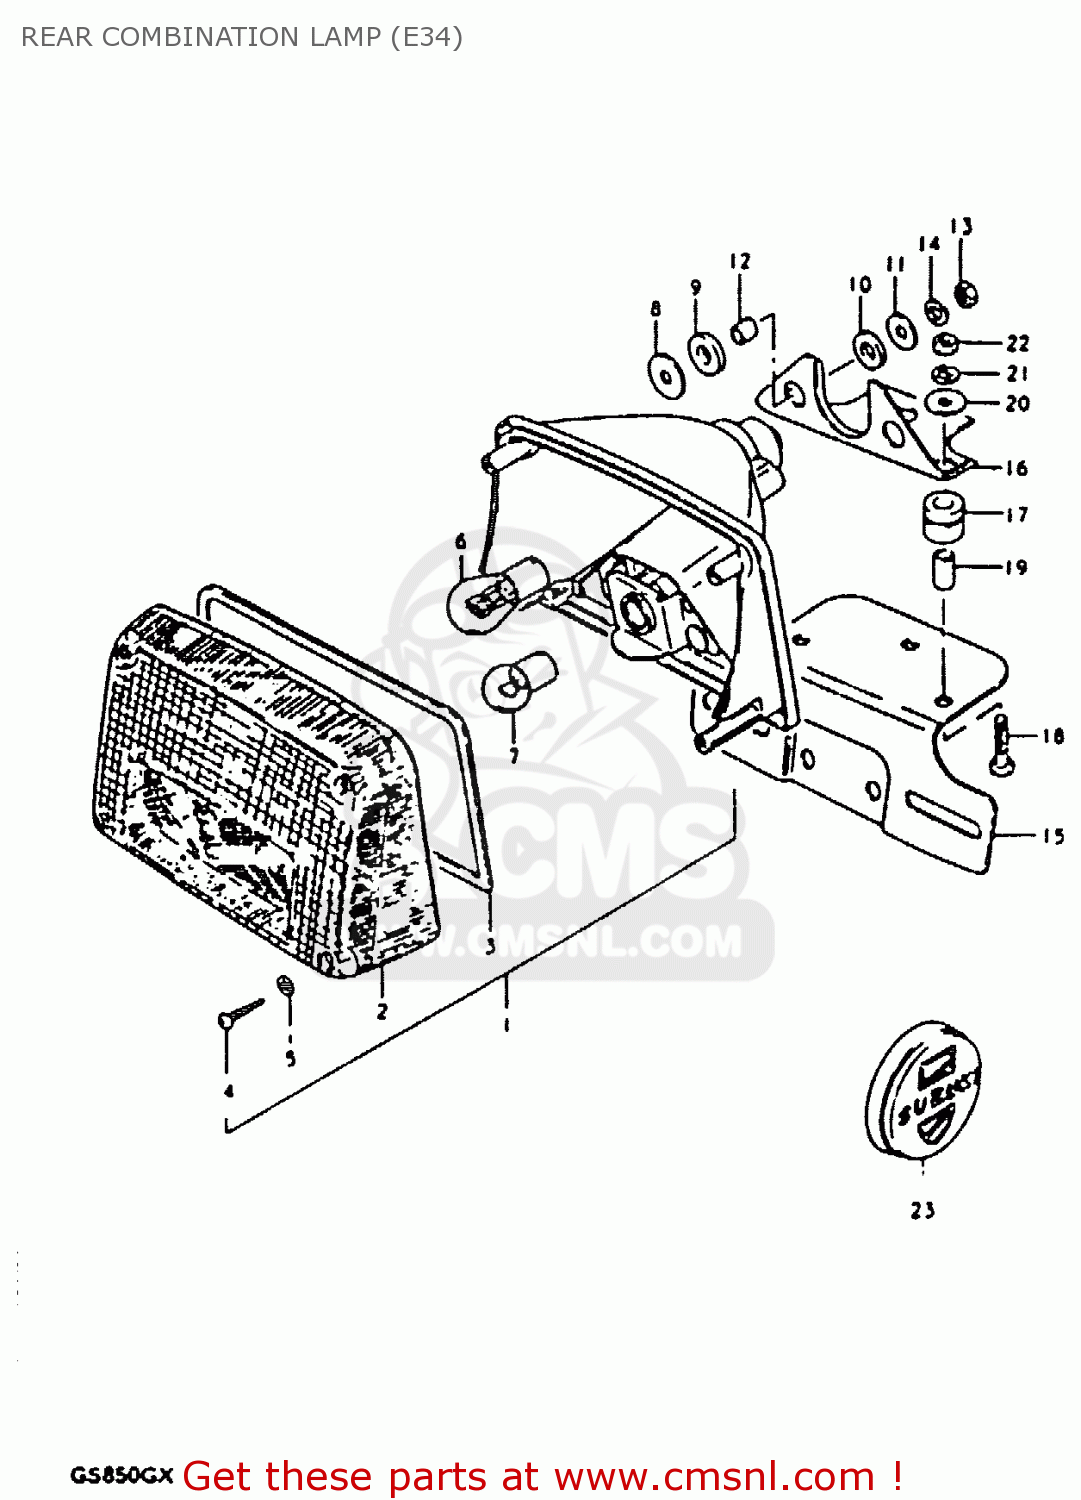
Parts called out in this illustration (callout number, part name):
1	LAMP, REAR COMBINATION
2	LENS
3	GASKET (NAS)
4	BOLT
5	GASKET (NAS)
6	BULB(12V21/5W)
7	BULB(12V10W,TOKAI DENSO)
8	WASHER
9	CUSHION
10	CUSHION
11	WASHER(6,5X22X1.6)
12	SPACER(6.1X9X7.5)
13	NUT
14	LOCK WASHER
15	BRACKET, LICENCE PLATE
16	BRACKET,LICENSE PLATE
17	CUSHION, BRACKET
18	BOLT
19	SPACER (6.4X9X15.5)
20	WASHER
21	LOCK WASHER
22	NUT
23	EMBLEM, REAR SIDE
